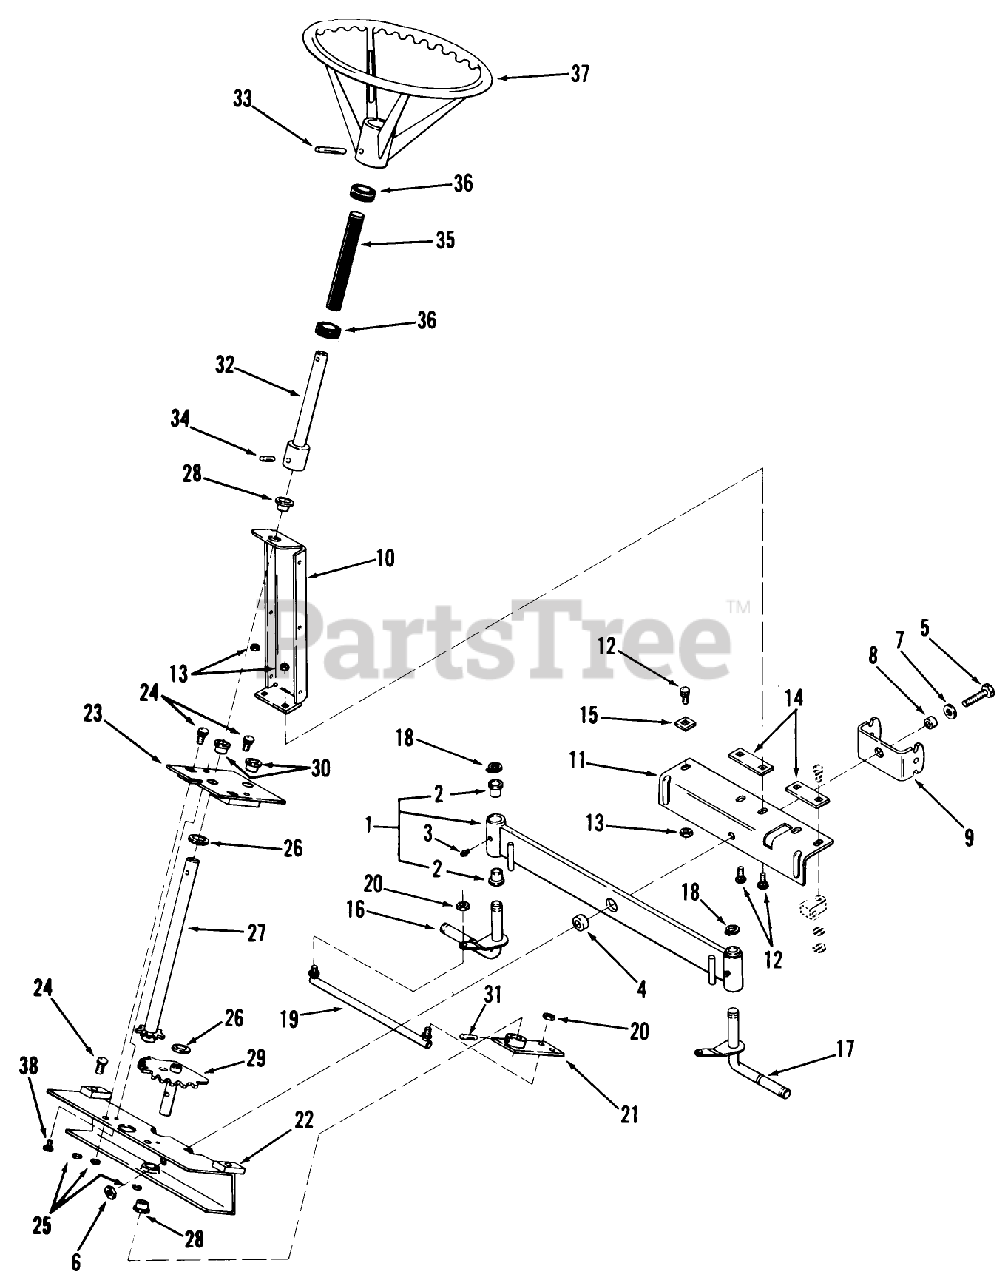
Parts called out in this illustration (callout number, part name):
2	BUSHING
19	ASSY-BALL JOINT *R
28	BEARING
29	ASSY-STEERING SEC *R (NS)
30	BUSHING
34	SPIROL PIN
38	Bolt
